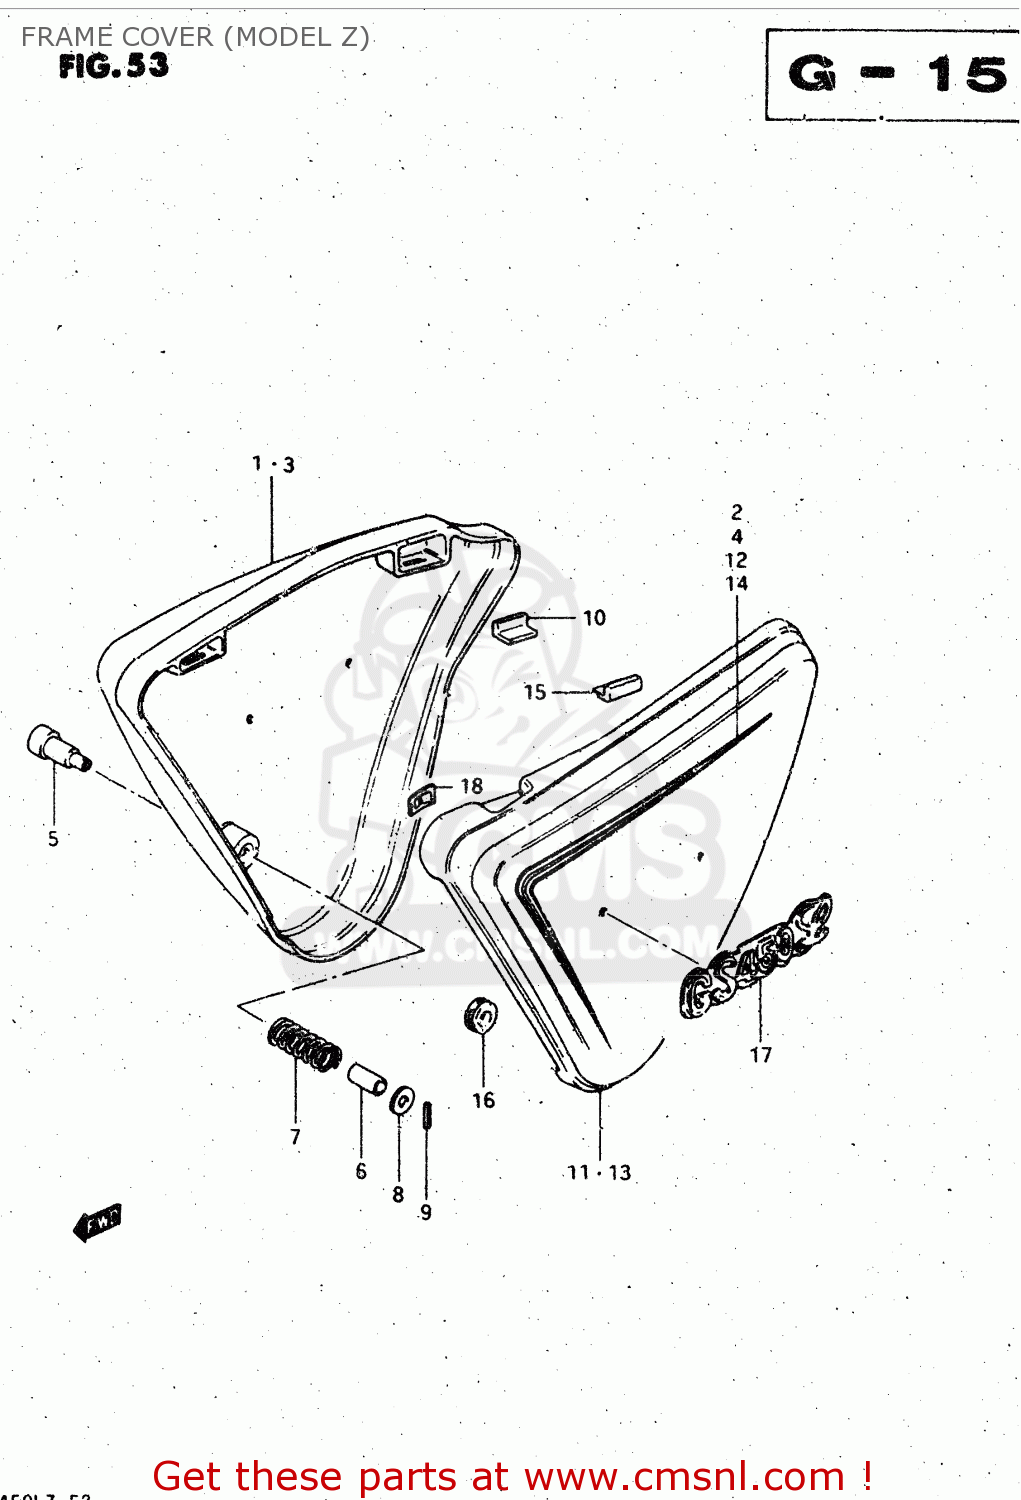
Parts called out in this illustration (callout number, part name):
1	COVER,FRAME,RIGHT
2	TAPE SET,FRAME COVER
3	COVER,FRAME,RIGHT
4	TAPE SET,FRAME COVER,RIGHT
5	KNOB,FRAME COVER,R
6	SPACER(14.9X17.3X13.5)
7	SPRING
8	WASHER (6.5X24X1.6)
9	PIN,SPRING(2.5X18)
10	CUSHION,FRAME COVER
11	COVER,FRAME,LEFT
12	TAPE SET,FRAME COVER,LEFT
13	COVER,FRAME,LEFT
14	TAPE SET,FRAME COVER,LEFT
15	CUSHION,FRAME COVER
16	CUSHION
17	EMBLEM,FRAME COVER
18	NUT
